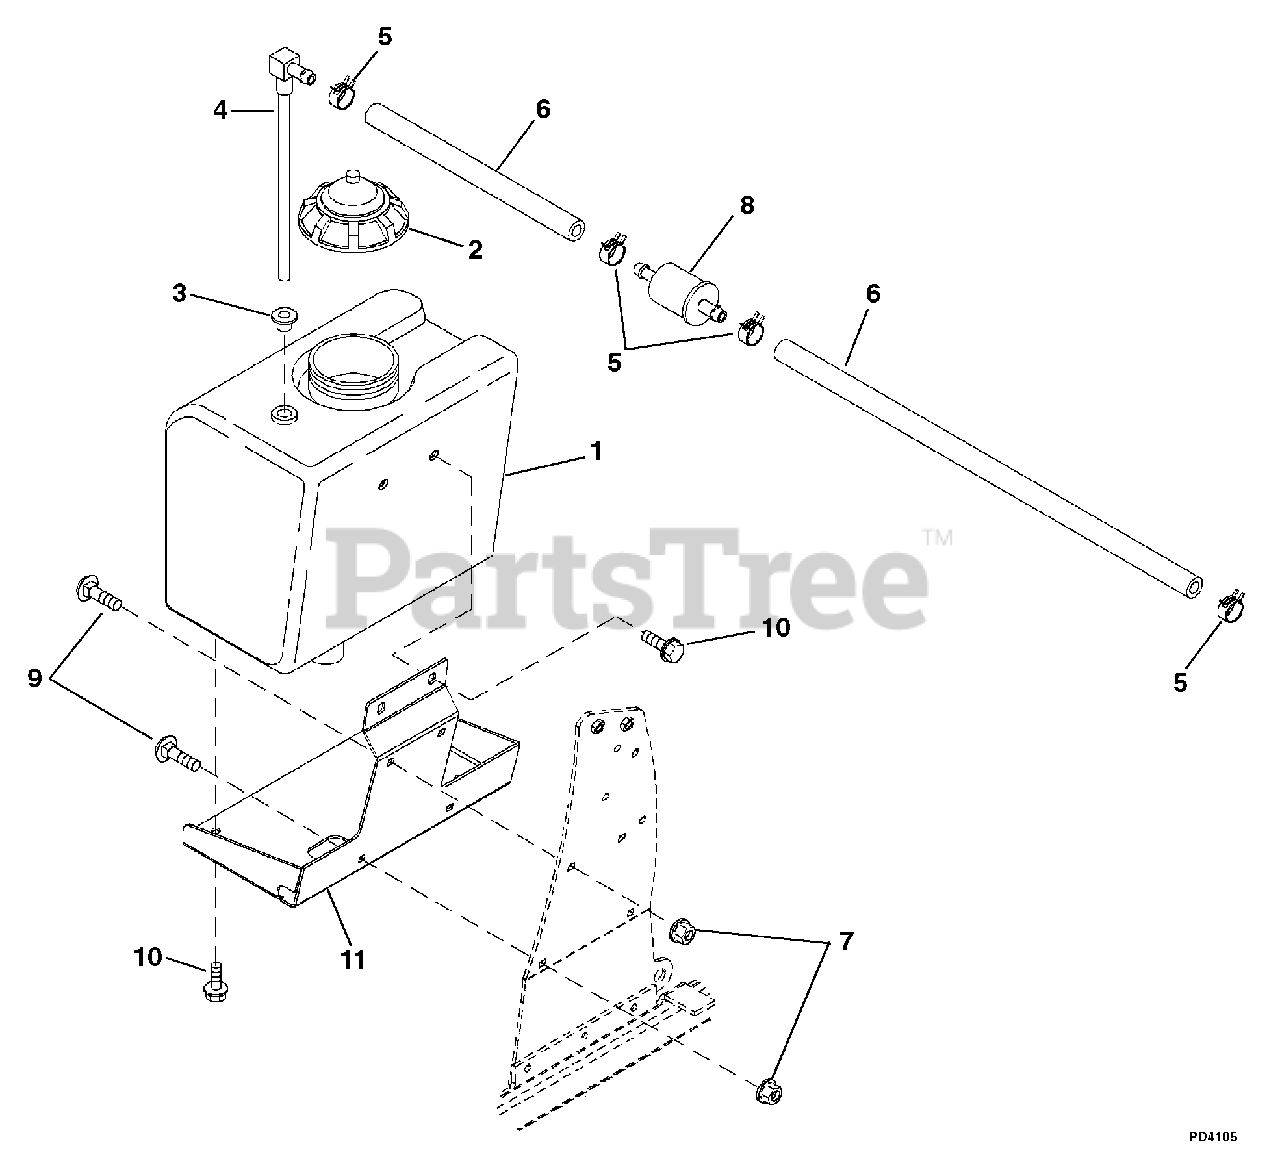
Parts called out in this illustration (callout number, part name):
1	Fuel Tank
2	Cap, Fuel
3	Grommet
4	Fuel Pickup
5	Clamp, Fuel Line
6	Hose, 10 FT Service #
7	Nut, Locking, Nylon 3/8-16
8	Filter, Fuel
9	Carriage Bolt, 3/8-16 x 1.00 Grade 5
10	Screw, Flange Hex Head JDS123 M8 x 1.25 x 16
11	Bracket, Fuel Tank Mounting
